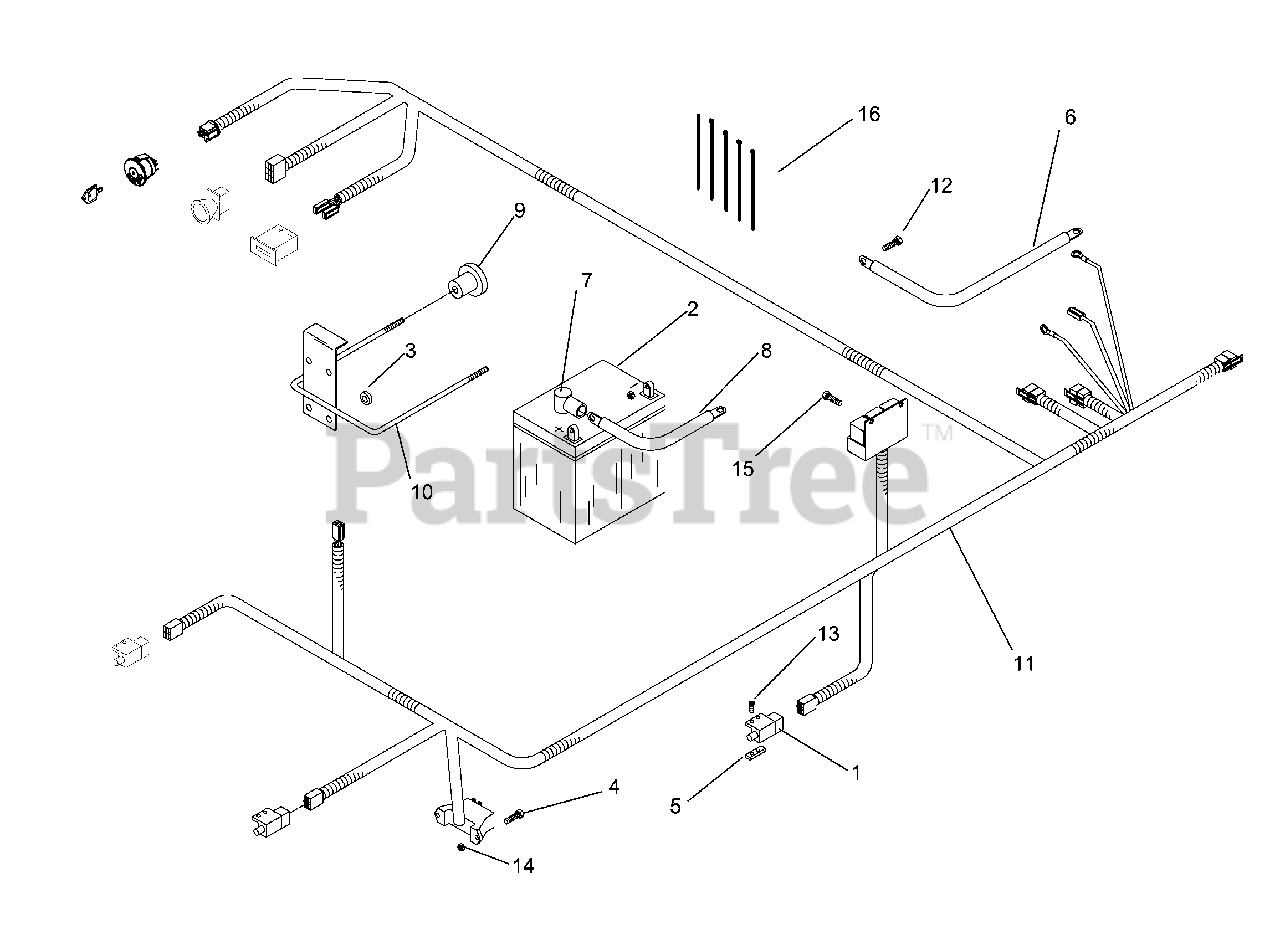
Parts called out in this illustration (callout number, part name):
1	SWITCH, INTERLOCK
2	BATTERY WET NOT SELLABLE
3	GROMMET, BUMPER
4	SCREW, #1--24 X 1/2 SLOTTED
5	TAPPED PLATE
6	CABLE-NEGATIVE
7	INSULATOR
8	POST.CABLE LONG
10	BATTERY HOLD DOWN
11	HARNESS, KODIAK
12	HCS 5/16C X 3/4
13	SCREW #10-24 X 5/8
14	NUT 10-24 NYLOC
15	SCREW #10 X 1/2 SELF TAPPING
16	TIE, PLASTIC
